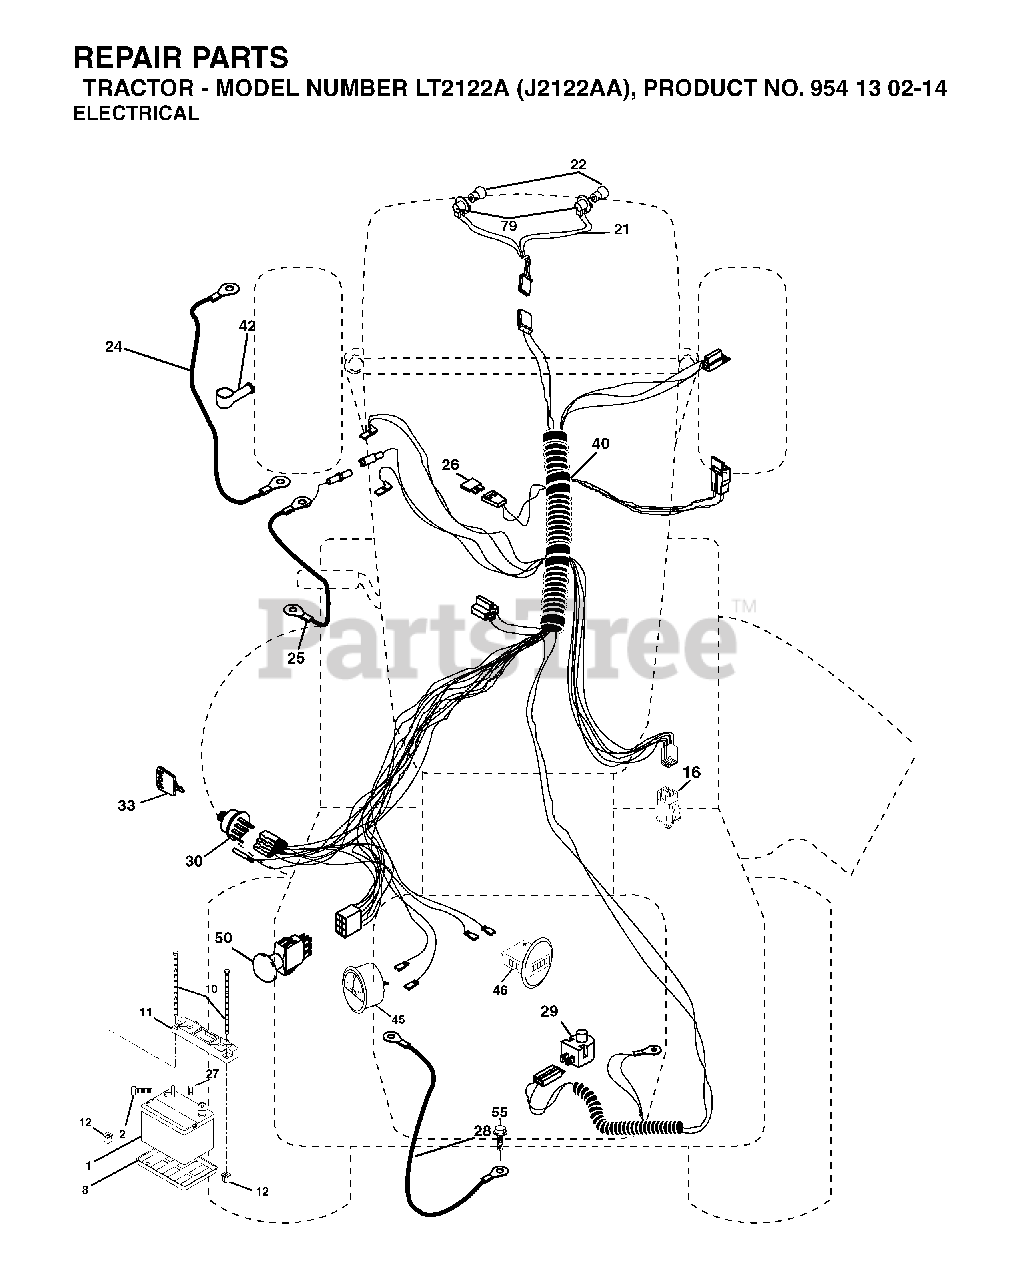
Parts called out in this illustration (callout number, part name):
1	BATTERY 12V .35 AMP
8	BATTERY TRAY T
10	BOLT 1/4-20 X 7.5
11	BATTERY HOLDDOWN
12	NUT, PUSH NYLON 1/4" BATTERY
16	SWITCH INTERLOOK PUSH-IN
21	HARNESS.W/LIGHT SOCKET
22	LIGHTBULB
26	FUSE 20AMP
27	NUT
28	CABLE GROUND 6 GA 21" 90T BLK
29	PLUNGER SWITCH (COLOR:OLIVE)
30	IGNITION SWITCH
33	KEY MLD GEN DELTA
42	COVER.TERMINAL.RED
46	HOURMETER SNAP-IN
50	PTO SWITCH
79	BULB HOLDER ASM.
